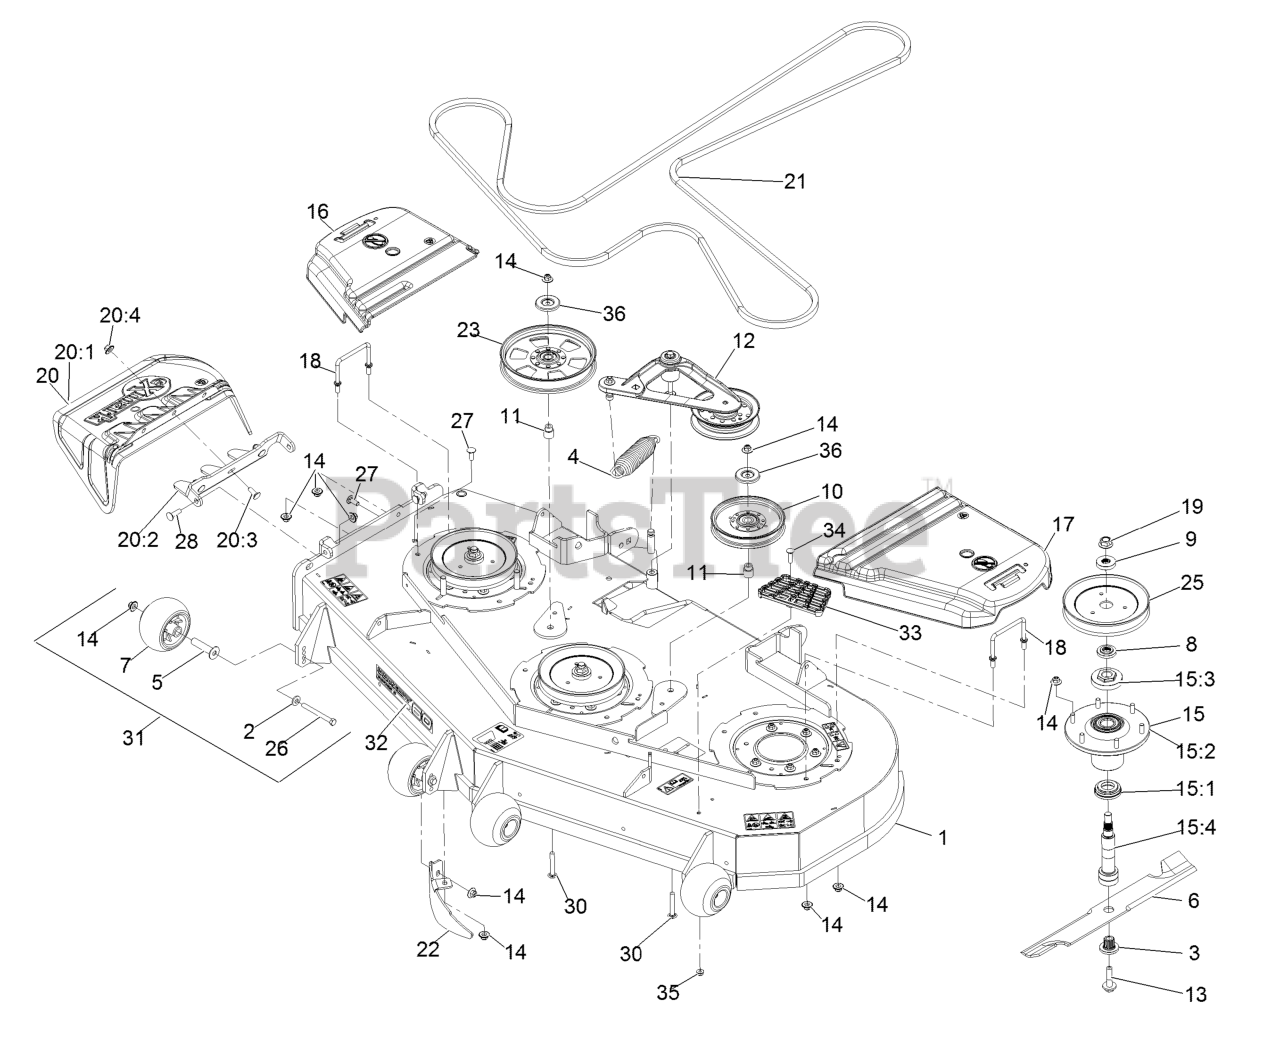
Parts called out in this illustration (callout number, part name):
1	Deck ASM,W/Decals 60
2	Washer-Spring Disc 3/8
3	Bushing, Splined
4	Spring-Extension
5	Axle, Roller
6	Blade, Solid
6	Blade, Low Lift
6	Blade, Mulching
6	Blade, Notched
6	Blade-Extreme 2, 20.50"
7	Roller-Anti-Scalp
8	Spacer, Splined Stepped
9	Spacer, Splined
10	Idler-Pulley
11	Bushing, Idler
12	Deck Idler ASM
13	Screw-Sems 1/2-20 X 2.19
14	Nut-Nyloc 3/8-16 Flg
15	ASM,Spindle Housing
15:1	Guard, Bottom
15:2	Asm, Cutter Housing
15:3	Nut, Spindle 7/8-14
15:4	Spindle,Double Spline
16	Cover-Belt, RH
17	Cover-Belt, LH
18	Wireform-Cover
19	Nut-Flange 5/8-18 Centerlock
20	ASM,Discharge Chute
20:1	Chute, Discharge
20:2	Bracket,Discharge Chute
20:3	Bolt-Carriage 3/8-16 X 1
20:4	Nut-Nyloc 3/8-16 Flg
21	Belt,V-5V-198.75
22	Dogleg - Lz60
23	Pulley-Idler, Flat
25	Sheave,Blade Drive 7.25
26	Screw-HH 3/8-16 X 3 3/4 GR 8
27	Bolt-Carriage 3/8-16 X 1
28	Bolt-Carriage 3/8-16 X 1 1/4
30	Bolt-Carriage 3/8-16 X 2 1/2
31	Kit, Anti-Scalp Roller
32	Decal, 606
33	Step-Deck
34	Bolt-Carriage 5/16-18 X 1 1/4
35	Nut-Nyloc 5/16-18 Flg
36	Shield-Dust
